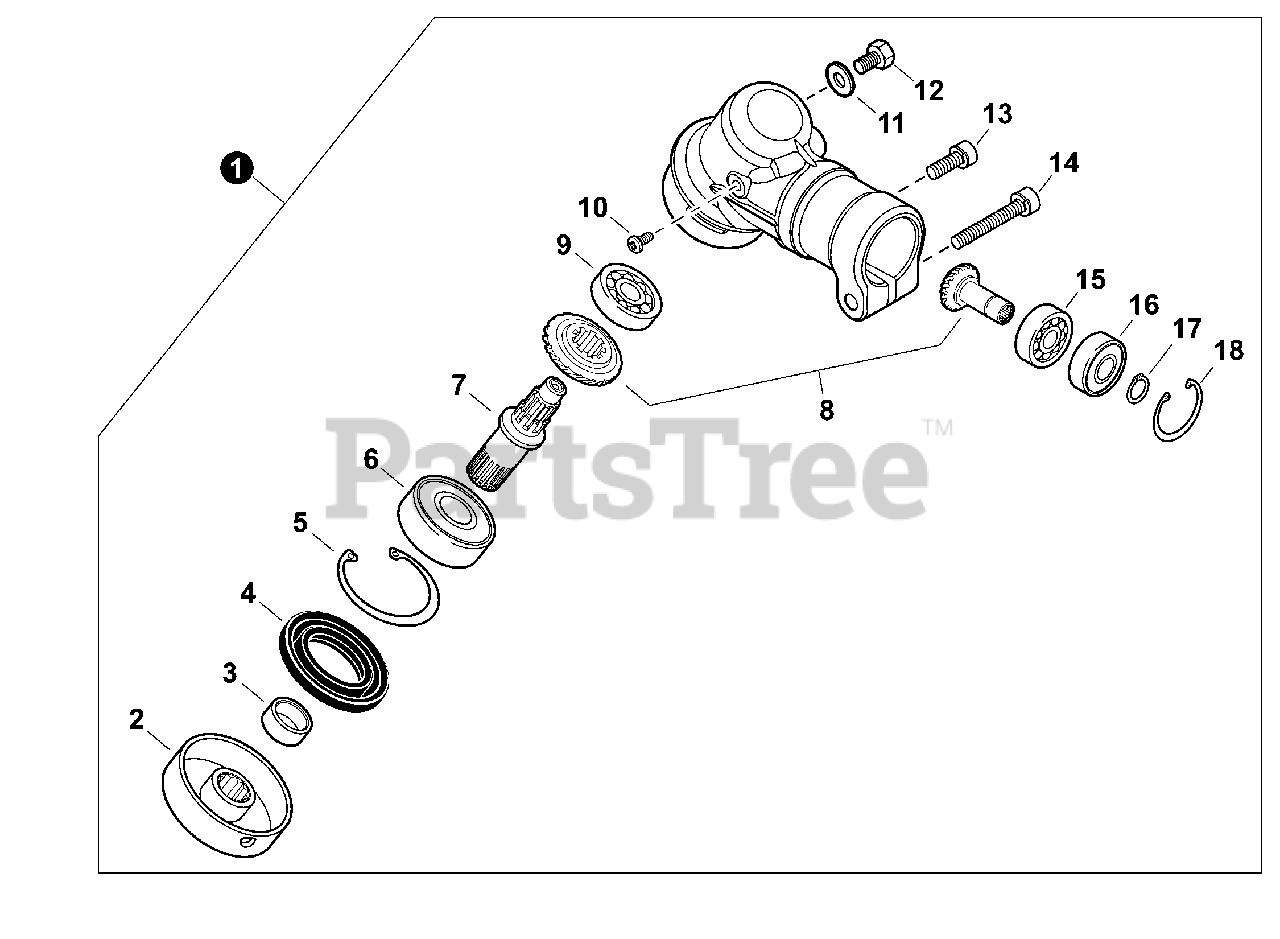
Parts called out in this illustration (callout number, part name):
1	GEAR CASE ASSY
4	SEAL, OIL
5	RING, SNAP Ø32
6	BEARING, BALL 6201
7	SHAFT, GEAR
8	GEAR SET
9	BEARING, BALL 609
10	SCREW M4×6
11	WASHER 6.5×11.5×0.8
12	BOLT M6×10
13	BOLT M5×10
14	BOLT M6×40
15	BEARING, BALL 6000
16	BEARING, BALL 6000ZZ
17	RING, SNAP Ø10
18	RING, SNAP Ø26
